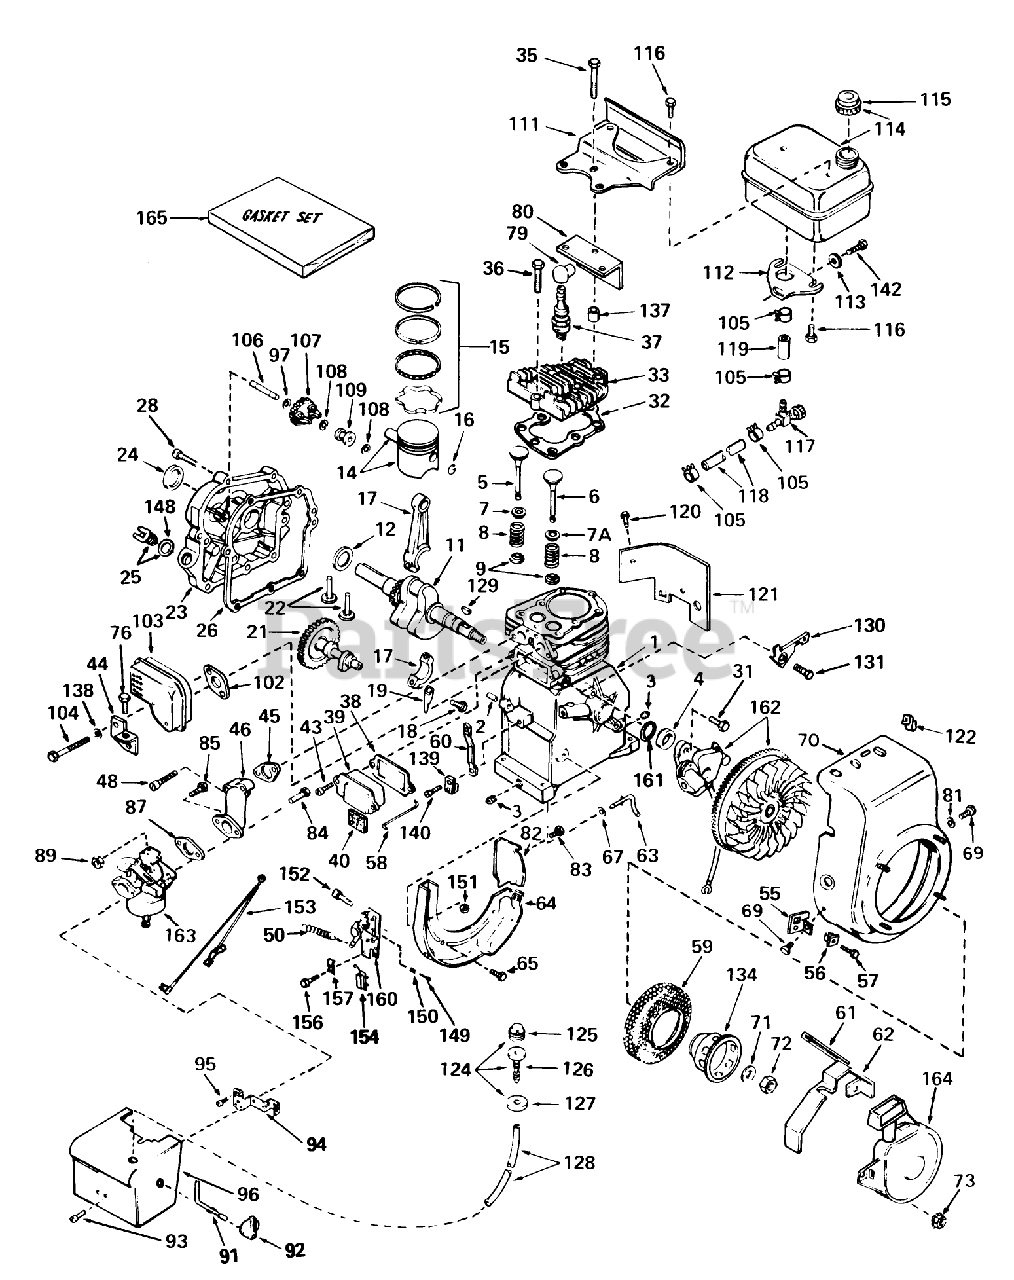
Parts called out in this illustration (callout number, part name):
1	Cylinder Assy. (Incl. Nos.2, 34)
2	Pin-Dowel
3	Plug-Drain, Oil (SQH 1/4-18)
4	Seal-Oil
5	Valve, Intake (Standard) (Incl. Nos. 7, 9 10)
5	Valve, Intake (1/32" Oversize) (Incl. Nos. 7, 9 10)
6	Valve, Exhaust (Standard) (Incl. Nos. 8, 9 10)
6	Valve, Exhaust (1/32" Oversize) (Incl. Nos. 8, 9 10)
7	Cap-Upper Valve Spring
7A	Cap, Upper Valve Spg (Exhaust)
8	Spring-Valve
9	Cap-Valve, Spring
11	Crankshaft Assy.
12	Washer-Thrust
14	Piston Pin Assy. (Incl. Ref. #16) (Std.)
14	Piston, Pin Ring Assy., (Incl. Ref. #15 16) (Std.)
14	Piston Pin Assy., (Incl. Ref. #16) (.010 Oversize)
14	Piston, Pin Ring Assy., (Incl. Ref. #15 16) (.010 Oversize)
14	Piston Pin Assy. (Incl. Ref. #16) (.020 Oversize)
14	Piston, Pin Ring Assy., (Incl. Ref. #15 16) (.020 Oversize)
15	Ring Set-Piston Std.
15	Ring Set-Piston .010 oversize
15	Ring Set-Piston .020 oversize
16	Ring-Retaining, Piston Pin
17	Rod Assy., Connecting (Incl. Nos. 18 19)
18	Bolt-Rod, Connecting
19	Dipper-Oil
21	Camshaft
22	Lifter-Valve
23	Cover, Cylinder (Incl. Nos. 24, 25, 106 148)
24	Seal-Oil
25	Plug-Fill, Oil
26	Gasket-Cylinder Cover
28	Screw
31	Screw
32	Oil Fill Tube
33	Head Cylinder
35	Screw (5/16-18 X 2)
36	Screw
37	Plug, Spark (J17LM or equiv.)
37	Plug, Spark (Champion RCJ-8)
38	Gasket Breather
39	Breather Assembly (Incl. Nos. 52 84)
40	Element-Breather
43	Screw
44	Bracket-Cover, Carburetor
45	Gasket-Intake
46	Pipe-Intake
48	Screw (1/4-20 x 1-19/32)
50	Spring-Extension
55	Bracket
56	Grommet
57	Screw
58	Link-Governor to Throttle
59	Screen-Starter
60	Lever, Governor
61	Seal, Snowguard
62	Guard-Starter
63	Rod-Governor
64	Baffle-Blower Housing
65	Screw (1/4-20x19/32)
67	Washer-Flat
69	Screw
70	Housing, Blower
71	Washer-Spring
72	Hex Nut
73	Nut and Lock Washer (1/4-28)
76	Screw (10-24 x 3/8)
79	Cover-Spark Plug
80	Baffle-Heat
81	Washer
82	Baffle-Extension
83	Screw-Hex Washer Hd.
85	Screw-Fil. Hd.
87	Gasket
89	Nut and Lock Washer (1/4-28)
91	Rod-Choke
92	Knob-Control
93	Screw (8-32 X 5/16)
94	Bracket-Choke
95	Screw (10-32 x 1/2)
96	Cover, Carburetor
97	Washer-Flat
102	Gasket-Exhaust
103	Muffler
104	Screw-Fil. Hd.
105	Clamp-Line, Fuel
106	Shaft-Governor
107	Governor Gear ASM
108	Ring-Retaining
109	Spool-Governor
111	Plate-Fuel Tank
112	Bracket, Fuel Tank Lower
113	Washer
114	53023/VAR.10/16HP O
115	Cap, Fuel
116	Screw (1/4-15x7/8)
117	Valve-Shut Off
118	Line-Fuel
119	Line-Fuel (8.62)
120	Screw
121	Extension-Blower
122	51004 GIL ROTARY TI
124	Primer Assy. (Incl. Nos. 89, 90 91)
125	Bulb, Primer
126	Body, Primer
127	Retainer, Primer Bulb
128	Line, Primer
129	Key, FIywheel
130	Bracket-Hold Down
131	Screw (10-24 x 9/16)
134	Cup, Starter
137	pacer
138	Washer
139	Clamp-Lever, Governor
140	Screw
142	Screw Assembly
148	Gasket
149	Screw
150	Spring-Compression
151	Nut-Lock
152	Screw
153	Wire-Ground
154	Terminal
156	Screw (10-32 x 3/8)
157	Conduit
160	Bracket Assy., Control (Incl. Ref. #149 thru 152 154)
161	Gasket Stator
162	Magneto
163	Carburetor (Incl. Ref. #87)
164	Starter Assy., Rewind
165	Gasket Set
